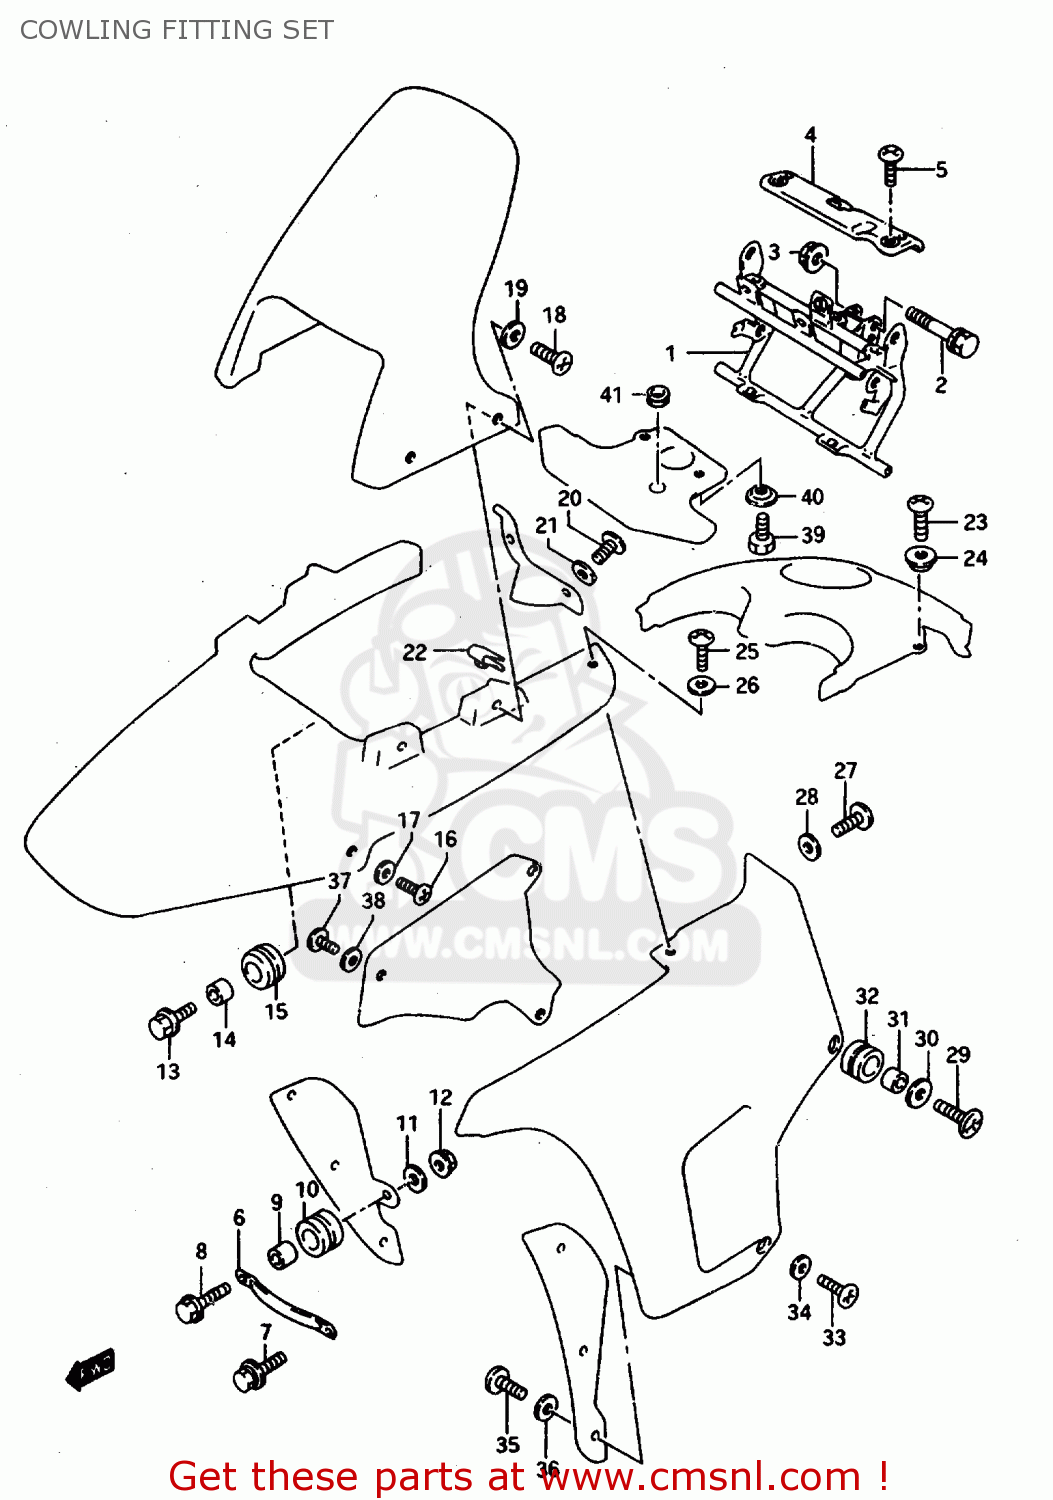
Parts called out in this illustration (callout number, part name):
1	BRACE,COWLING
2	BOLT
3	NUT
4	COVER,COWLING BRACE
5	SCREW 6X12
6	BRACE,COWLING SIDE
7	BOLT
8	BOLT
9	SPACER(6.1X9X7.5)
10	CUSHION
11	WASHER(6.5X20X1.6)
12	NUT
13	BOLT(6X25)
14	SPACER(6.5X9X10)
15	CUSHION
16	SCREW(5X16)
17	WASHER(7X13X0.6)
18	SCREW
19	WASHER(5.2X11X1)
20	SCREW(5X12)
21	WASHER(5.5X16X1.2)
22	NUT,HEADLAMP HOUSING,UPPER
23	SCREW(5X12)
24	WASHER(5.2X14X1.5)
25	SCREW(5X16)
26	WASHER(7X13X0.6)
27	SCREW(5X16)
28	WASHER
29	SCREW(6X20)
30	WASHER(6.5X18X1)
31	SPACER(6.5X9X10)
32	CUSHION
33	SCREW(5X14)
34	WASHER(5.2X14X1.5)
35	SCREW
36	WASHER(5.5X16X1.2)
37	SCREW
38	WASHER(5.5X16X1.2)
39	BOLT
40	WASHER
41	GROMMET
